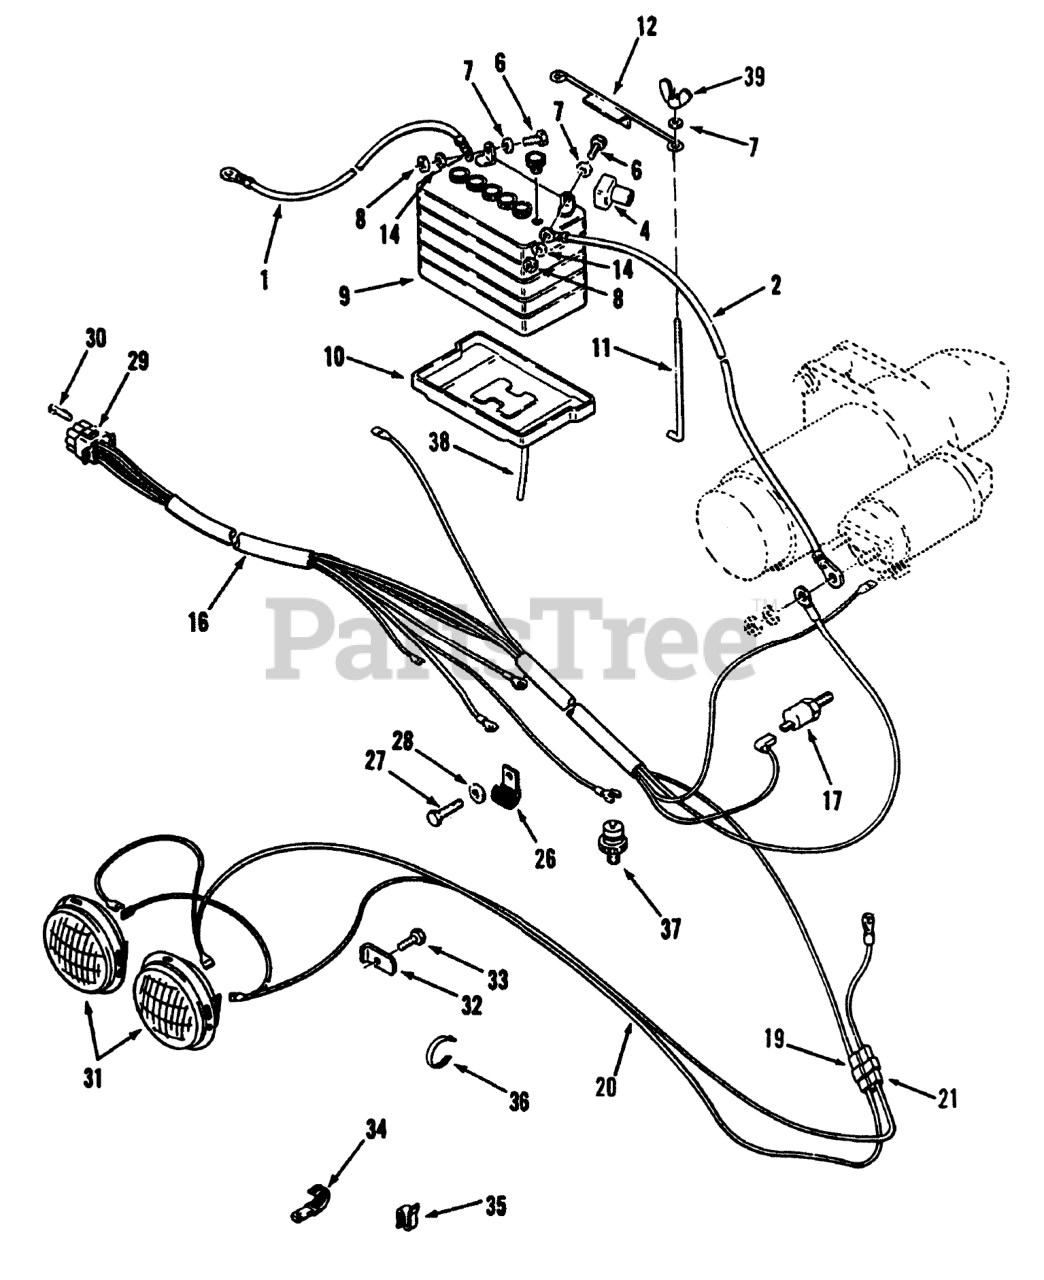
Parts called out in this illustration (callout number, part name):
1	ASS'Y-WIRE
2	ASS'Y-WIRE
4	Boot
6	SCREW-HH
7	WASHER-FLAT
8	NUT-LOCK, NI
9	Battery
10	THRUST WASHER
11	HOOK-BATTERY RETAIN
12	HOLDDOWN-BATTERY
14	WASHER-LOCK
16	WIRING HARNESS
17	HIGH TEMPERATURE
19	MALE CONNECTOR
20	HARNESS-HEADLIGHT
21	CONNECTOR BODY
26	CLIP-WIRE
27	SCREW-HWH
28	LOCKWASHER 1/4 IT
29	CONNECTOR CAP
30	CONTACT SOCKET
31	HEADLAMP
32	LOCK-HEADLIGHT
33	Bolt
34	CLIP
35	SPEED CLIP
36	PLASTIC TIE
37	SWITCH
38	TUBE-21" BATTERY DRAIN
39	NUT-WING
40	ELBOW-45 DEG
